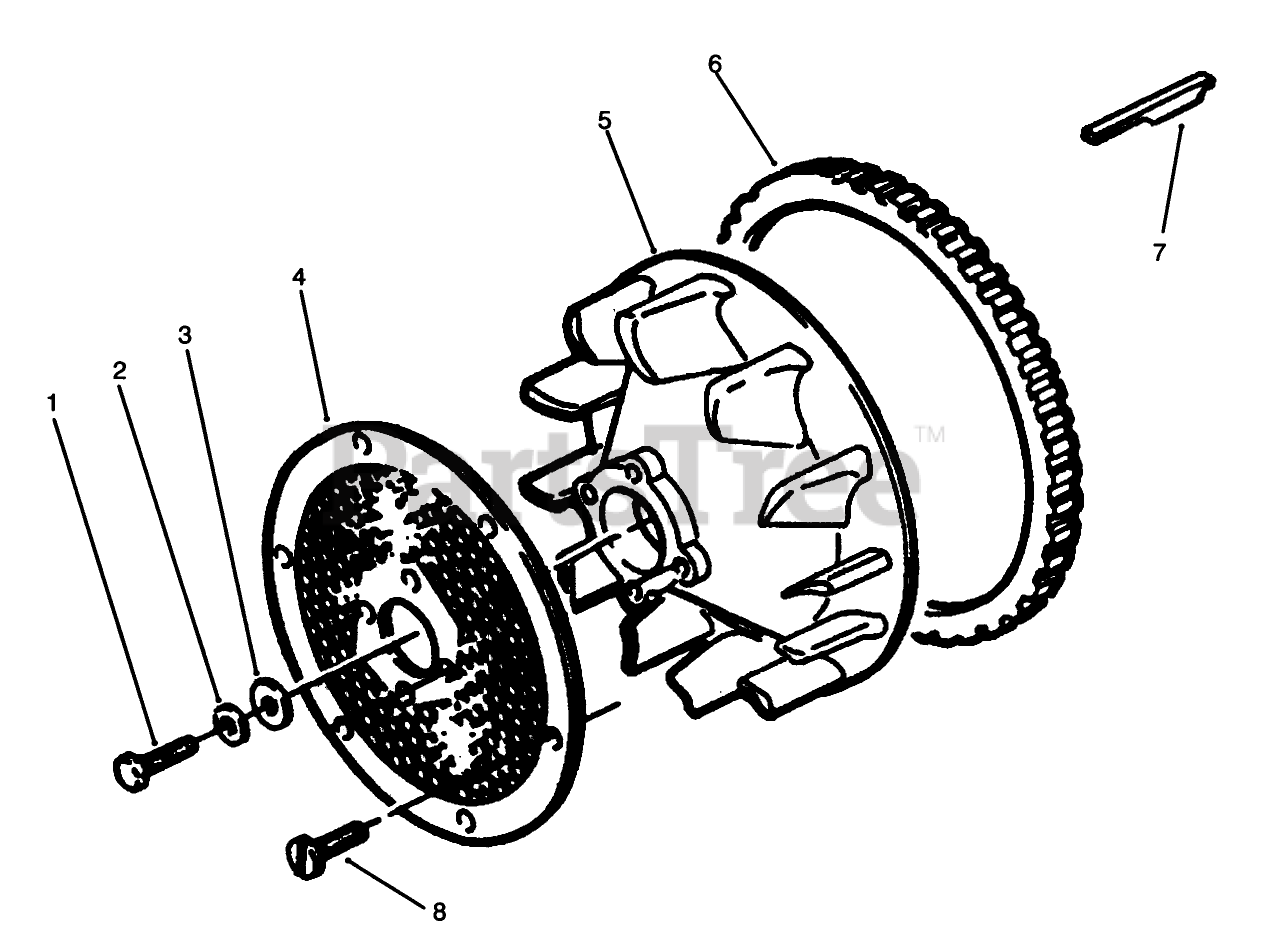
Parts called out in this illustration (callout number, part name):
2	WASHER-FLAT
3	WASHER-FLAT
4	SCREEN-AIR INLET
7	KEY-FLYWHEEL
